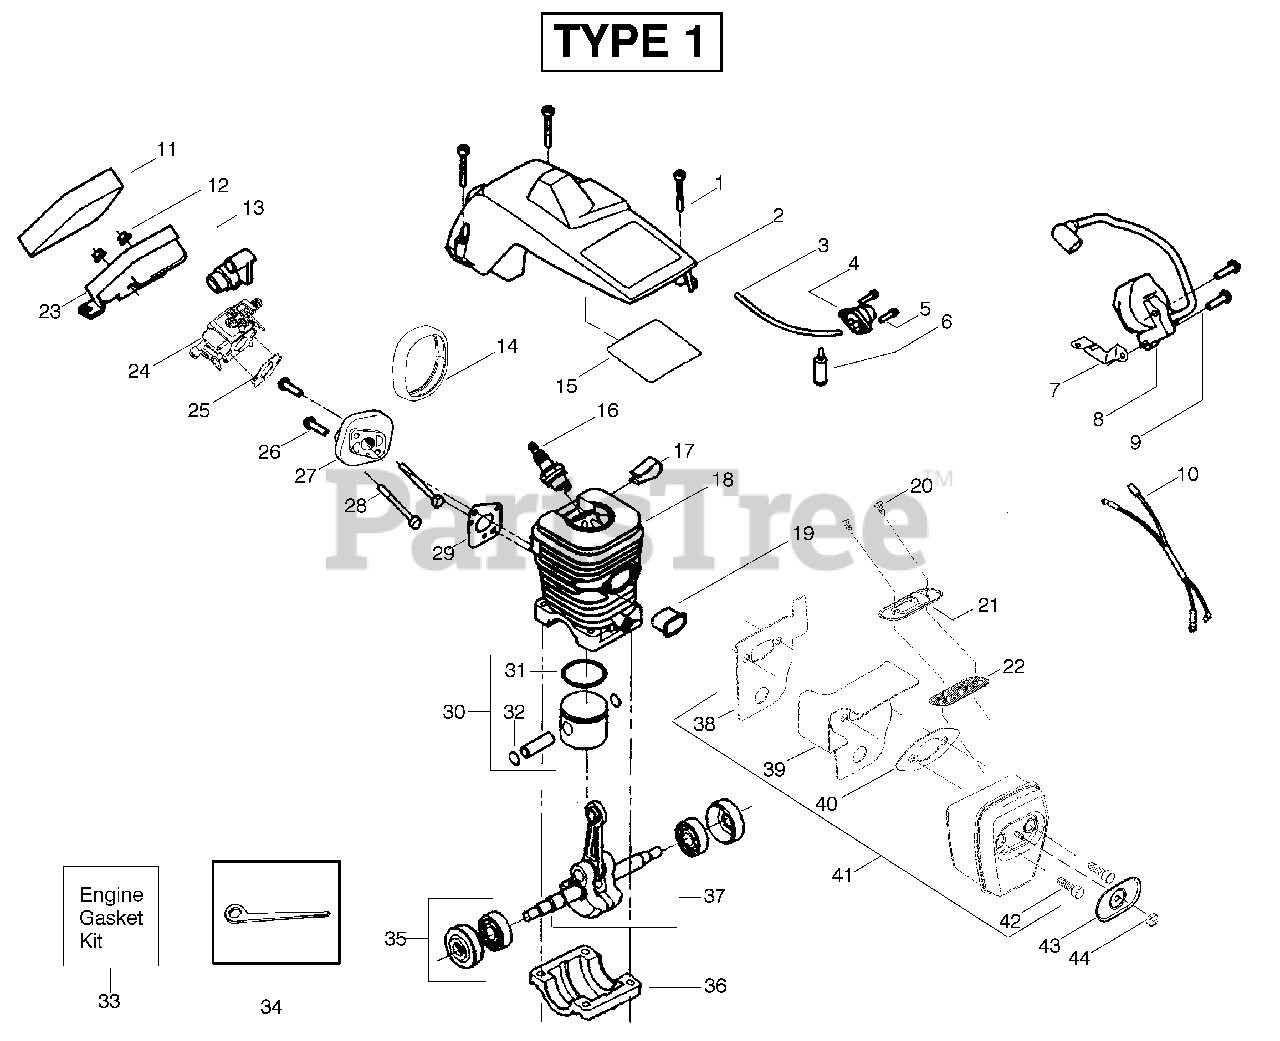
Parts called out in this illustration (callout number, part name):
2	Assy-Cylinder Shield
3	Kit-Fuel Line
4	Assy- Air Purge
6	Assy-Fuel Pick-up
7	Strap-Ground
8	Ignition Module
10	Assy-Wire Harness
11	Foam- Air Filter
13	Grommet-Carb Adjust
14	Seal-Carb Adapter
15	Reflector-Heat
16	Spark Plug
17	Clip-High Tension Lead
18	Cylinder
19	Insulator-Heat
20	Screw-Outlet cover
21	Cover - Outlet
22	Kit-Spark Arrestor
23	Air Filter Housing
24	Kit-Carburetor (Wt-600)
24	Kit-Carburetor (W14A)
25	Gasket-Carb.
27	Carb. Adapter
29	Gasket-Carb Adap.
30	Kit-Piston
31	Ring-Piston
32	Retainer-Piston Pin
33	Kit-Engine Gasket
34	Bar Wrench
35	Assy-Seal & Bearing
36	Cap-Crankcase
37	Assy-Crankshaft
38	Backplate
39	Guide-Outlet
40	Gasket-Muffler
41	Assy-Muffler
42	Bolt-Muffler
43	Cover-Bolt
44	Nut-Brass
